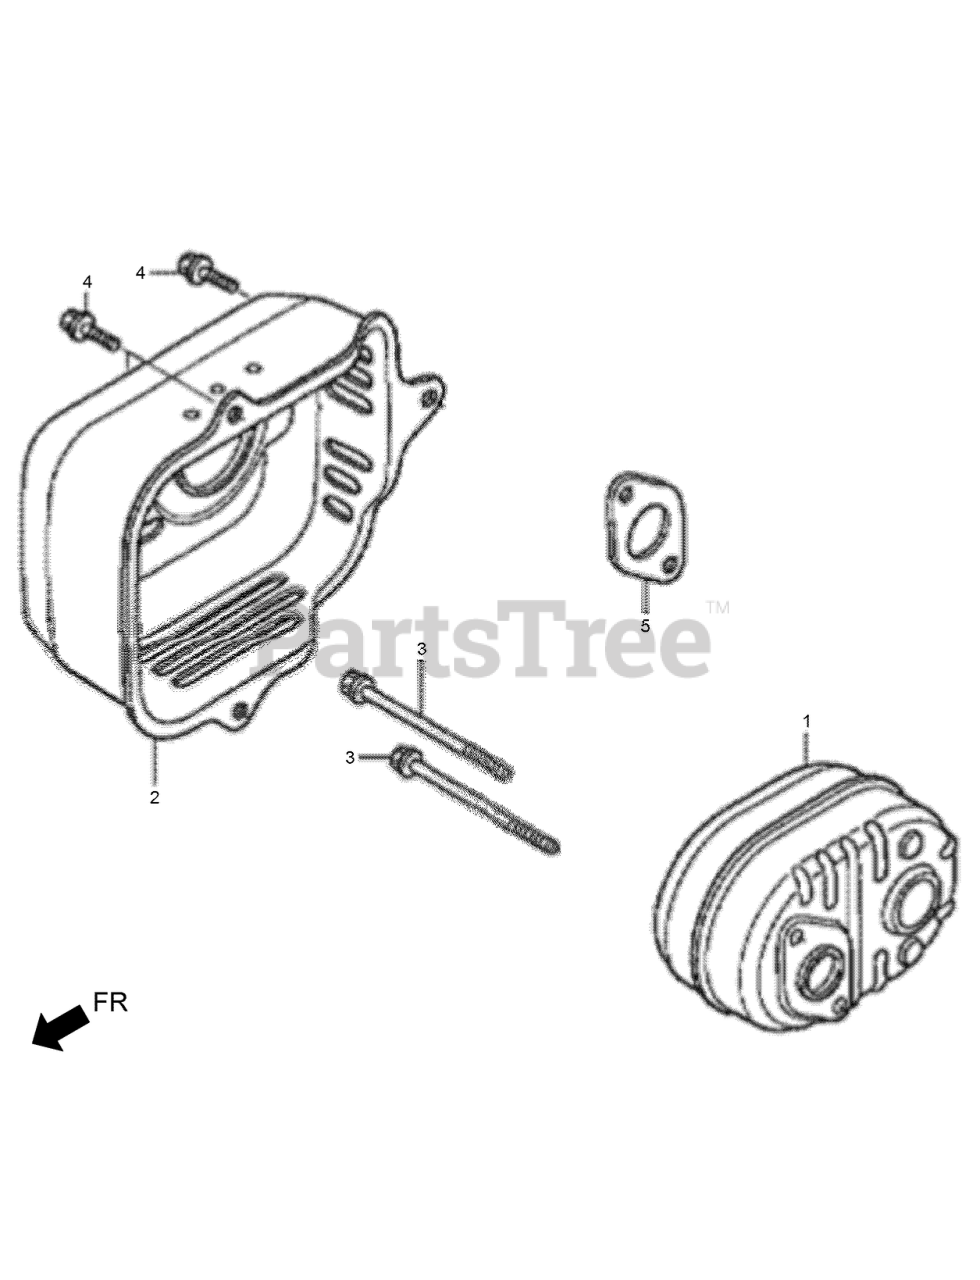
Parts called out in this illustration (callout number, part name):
1	MUFFLER ASM
2	MUFFLER PROTECTOR ASM
3	BOLT-FLANGE-6X79
4	BOLT-FLANGE-6X12
5	GASKET-MUFFLER
